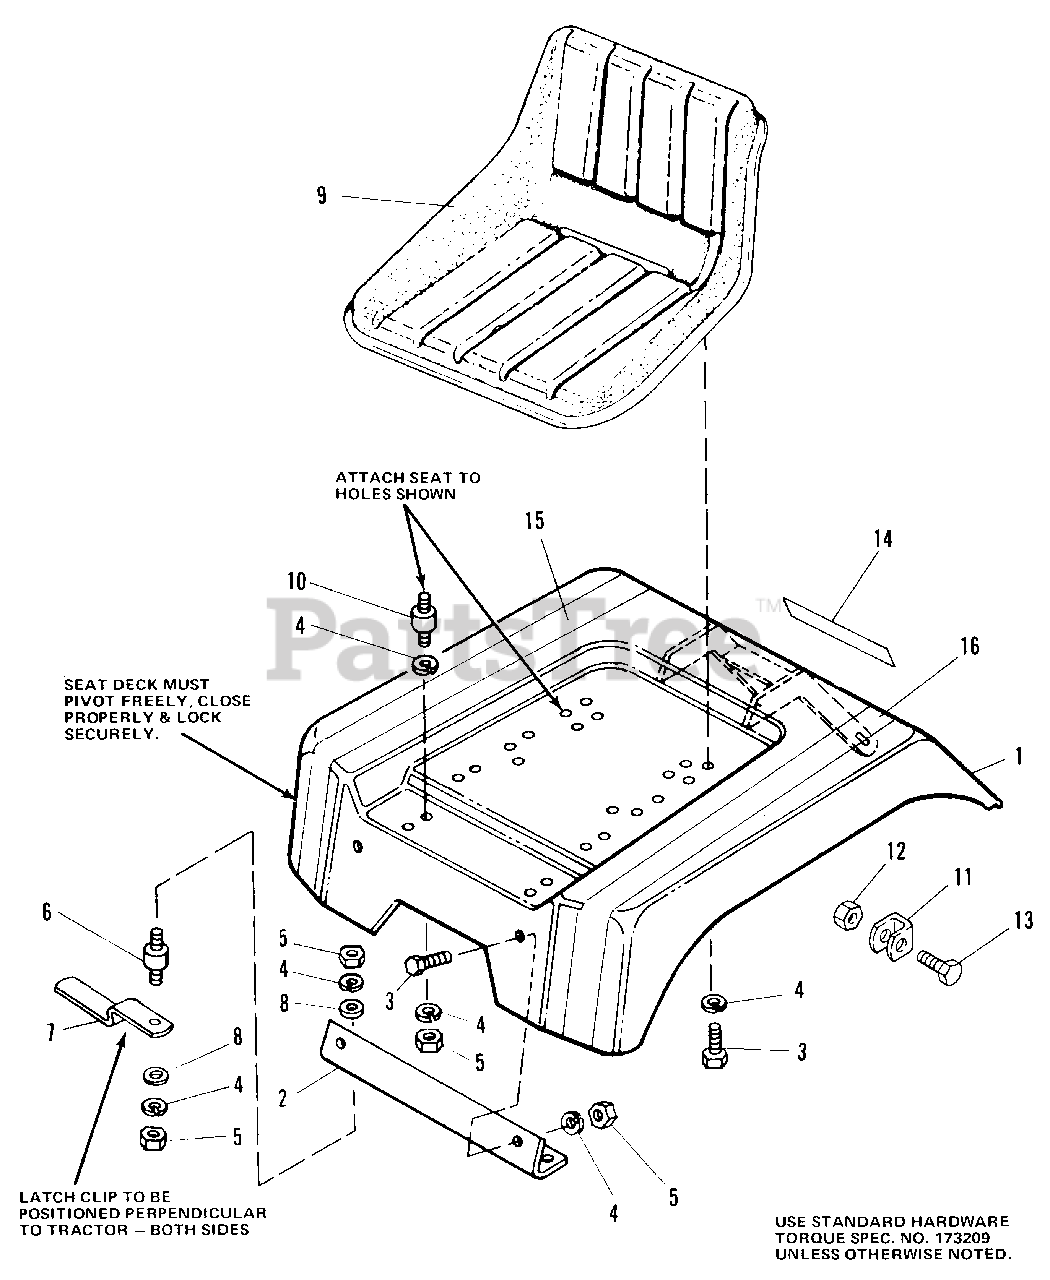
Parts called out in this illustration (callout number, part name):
1	SEAT, Deck
2	BRACKET, Frt. Seat Deck
3	CAPSCREW, .312-18 x 625
4	LOCKWASHER, .312
5	NUT, Hex, Full, .312-18
6	CONNECTOR, Cushion
8	WASHER, .250 Std.
10	CONNECTOR, Cushion
11	STOP, Seat Deck
12	LOCKNUT, Hex, .375-16
13	CAPSCREW, Hex, .375-16 x 1.25
14	DECAL, Simplicity
15	DECAL, Strip R.H.
16	DECAL, Strip L.H.
